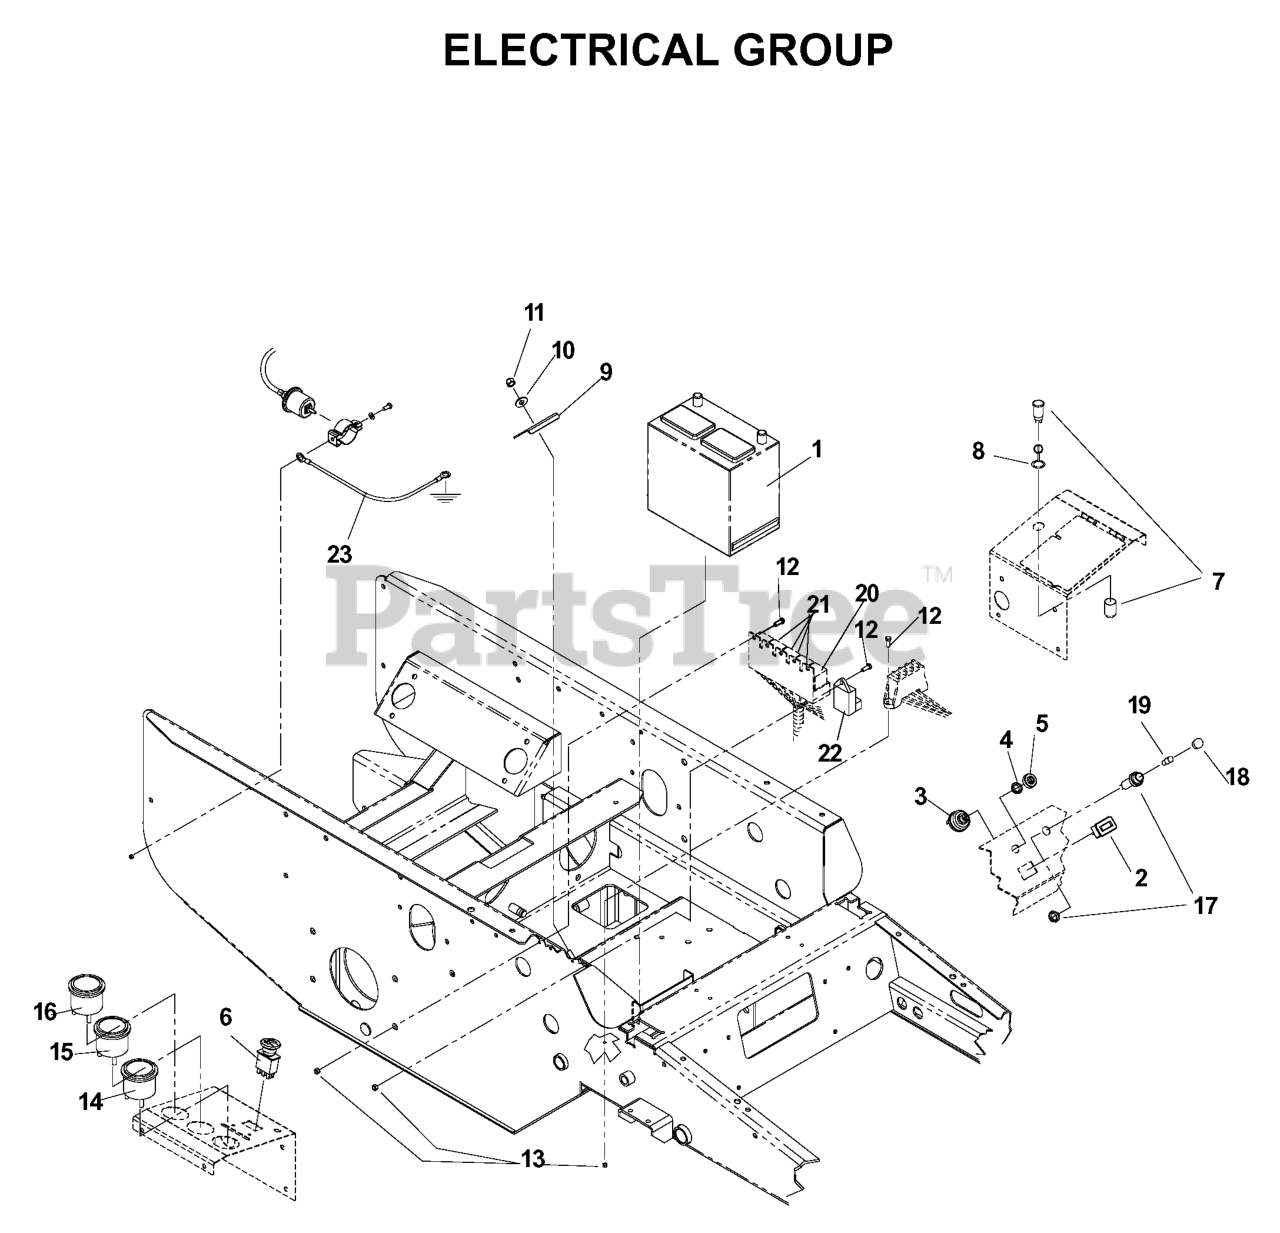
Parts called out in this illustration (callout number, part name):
2	DIGITAL HOUR METER
3	IGNITION SWITCH KIT
4	DNO IGNITION NUT
5	CAP IGNITION NUT
6	RP.SWITCH, BLADE
7	POWER SOURCING HSG
8	POWER SOURCE CAP
10	WASHER 5/16 FLAT
11	NUT 5/16 NYLOC
12	SCREW 10-24 X 3/4
13	NUT 10-24 NYLOC
14	TEMP GAUGE DATCON #100182
15	GAUGE, AMPMETER DATCON 100160
16	GAUGE, OIL PRES DATCON 100172
17	LAMP SPROCKET
22	TIMER/GLOW PLUG
